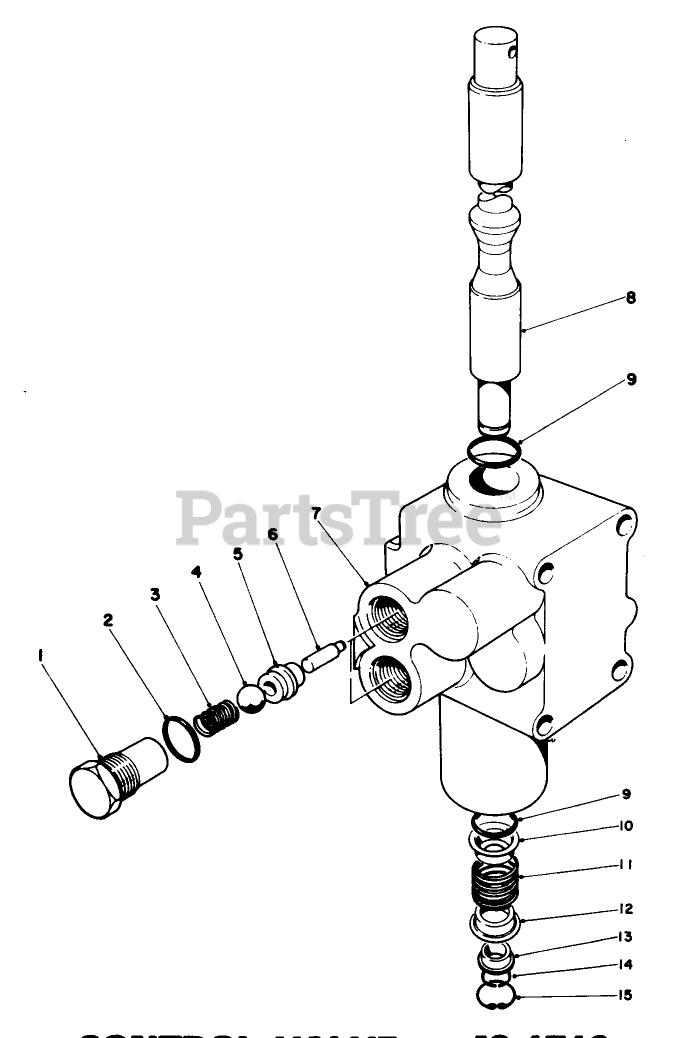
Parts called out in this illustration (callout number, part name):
2	O-RING
3	SPRING
5	SEAT-VALVE
7	Bode
8	SPOOL
9	O-RING
10	RETAINER
11	SPRING
12	RETAINER
13	SPACER
14	RING-SNAP
15	RING-SNAP
